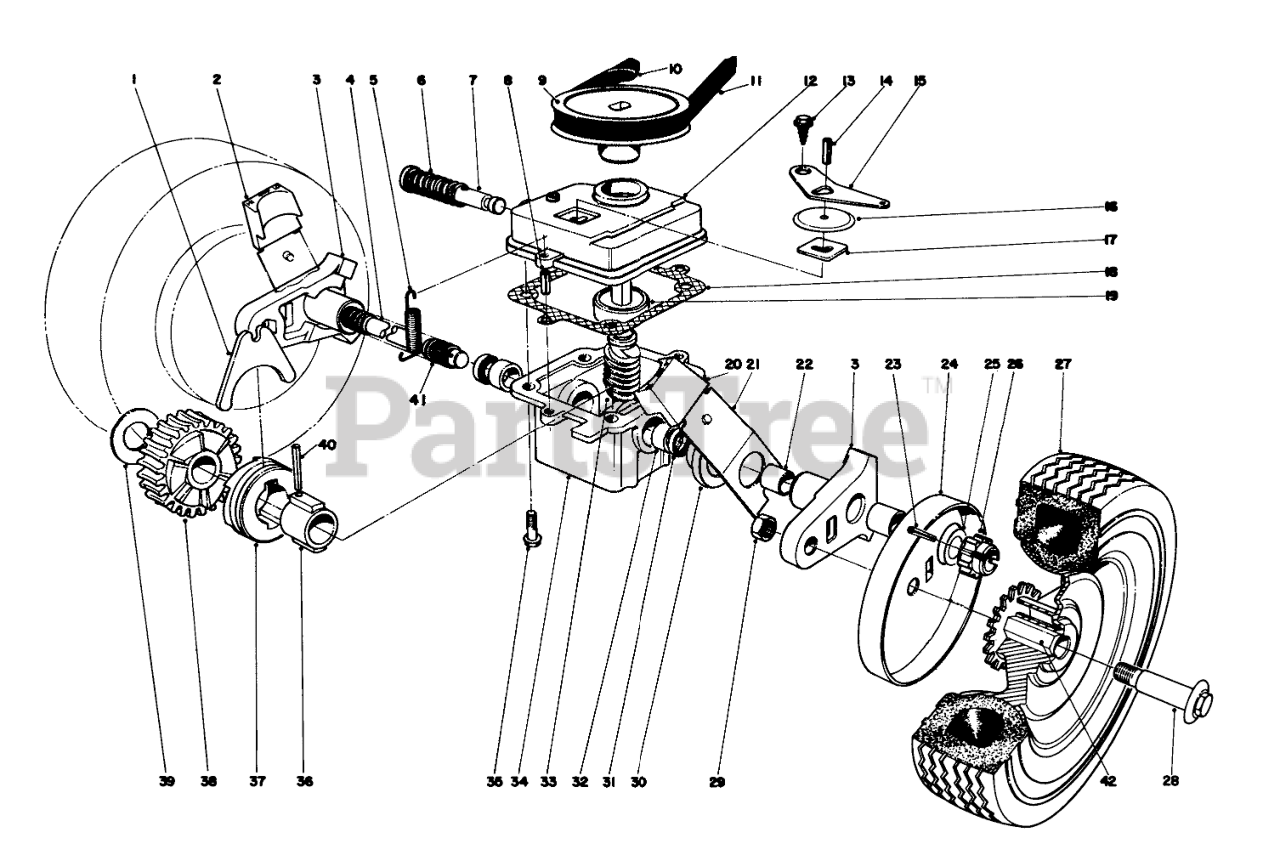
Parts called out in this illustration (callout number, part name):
1	SHIFTER FORK
2	Arm Knob
3	Pivot Arm (Incl. Ref. No. 22)
4	Drive Shaft
5	TENSION SPRING
6	SPRING
7	Shift Rod
8	3/16 X 1/2 ROLL PIN
9	PULLEY
10	PUSH-ON 93-3236
11	V BELT
12	GEAR CASE COVER
13	Screw
14	PIN-ROLL
15	SHIFTER ARM
16	TRANS DUST COVER
17	Latch Plate
18	GASKET
19	Bearing
20	Arm Knob
21	Spring Arm
22	BUSHING
23	PIN-GROOVED
24	WHEEL COVER
25	WASHER-THRUST
26	Pinion
27	Bushing
29	Nut
30	End Cap
31	Seal
32	Bushing
33	WORM SHAFT
34	Gear Case (Incl. Ref. 31-32)
35	Screw
36	SLEEVE
37	CLUTCH JAW
39	THRUST WASHER
40	COIL PIN
41	COVER-SHAFT, DRIVE
42	WHEEL BUSHING
